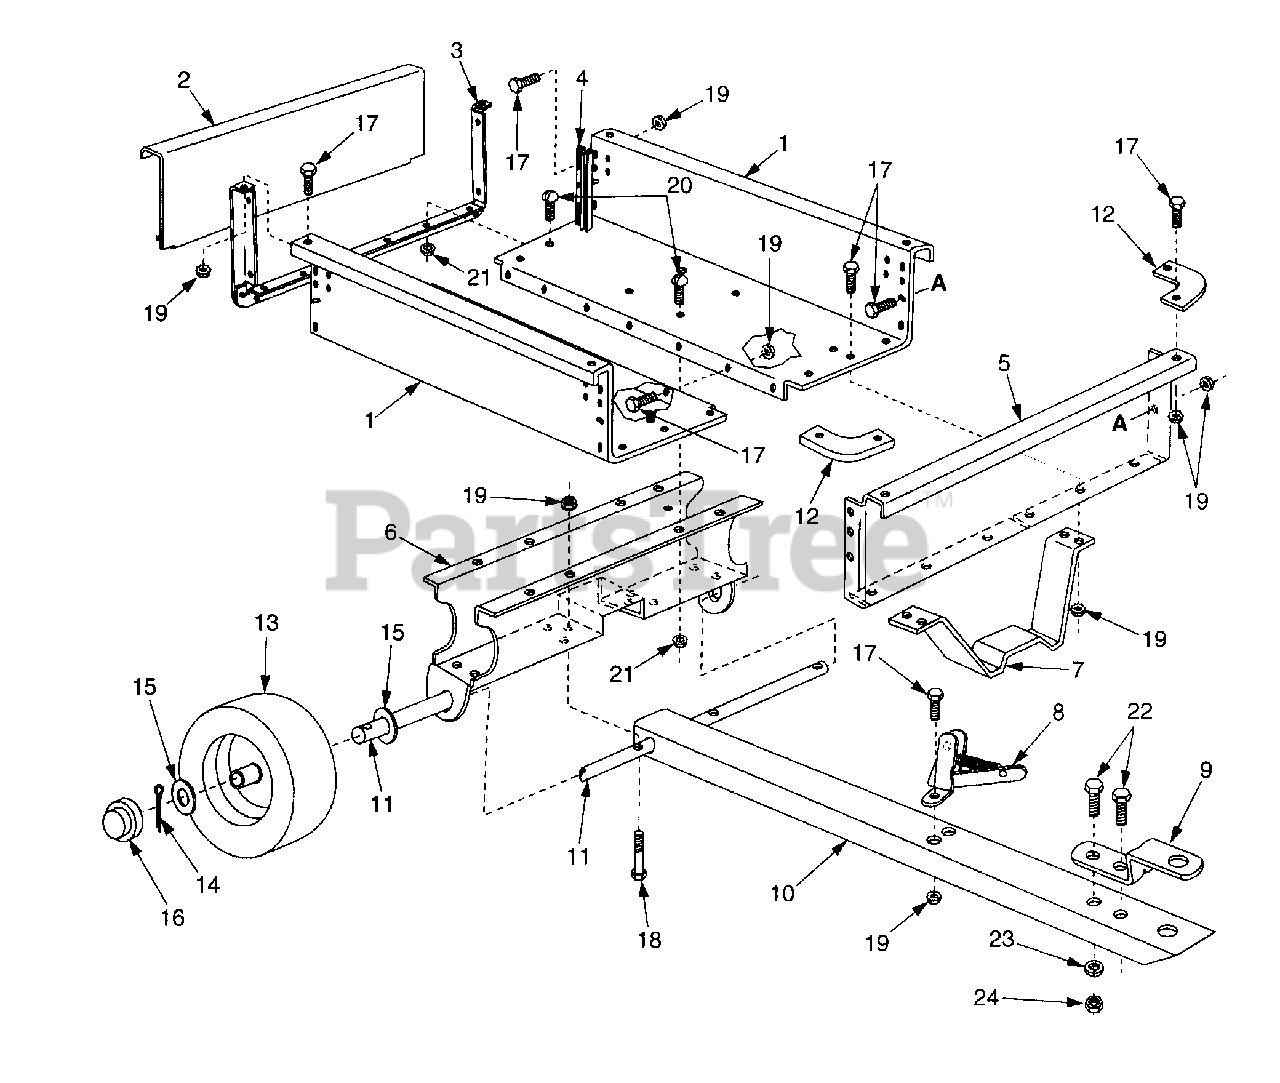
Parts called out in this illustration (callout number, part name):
14	Cotter Pin, 1/8" Dia. x 1-1/2"
15	Washer, Flat 1"
16	Hub Cap
17	Hex Bolt, 1/4-20 x 1/2"
18	Hex Bolt, 1/4-20 x 1-3/4"
19	Hex Nut, 1/4-20 Thread (Sems)
20	Slt.Truss Hd. Bolt 5/16-18 x 3/4" Lg.
21	Hex Nut, 5/16-18 Thread (Sems)
22	Hex Bolt, 3/8-16 x 1" Lg.
23	Lock Washer, 3/8"
24	Hex nut, 3/8-16 Thread
